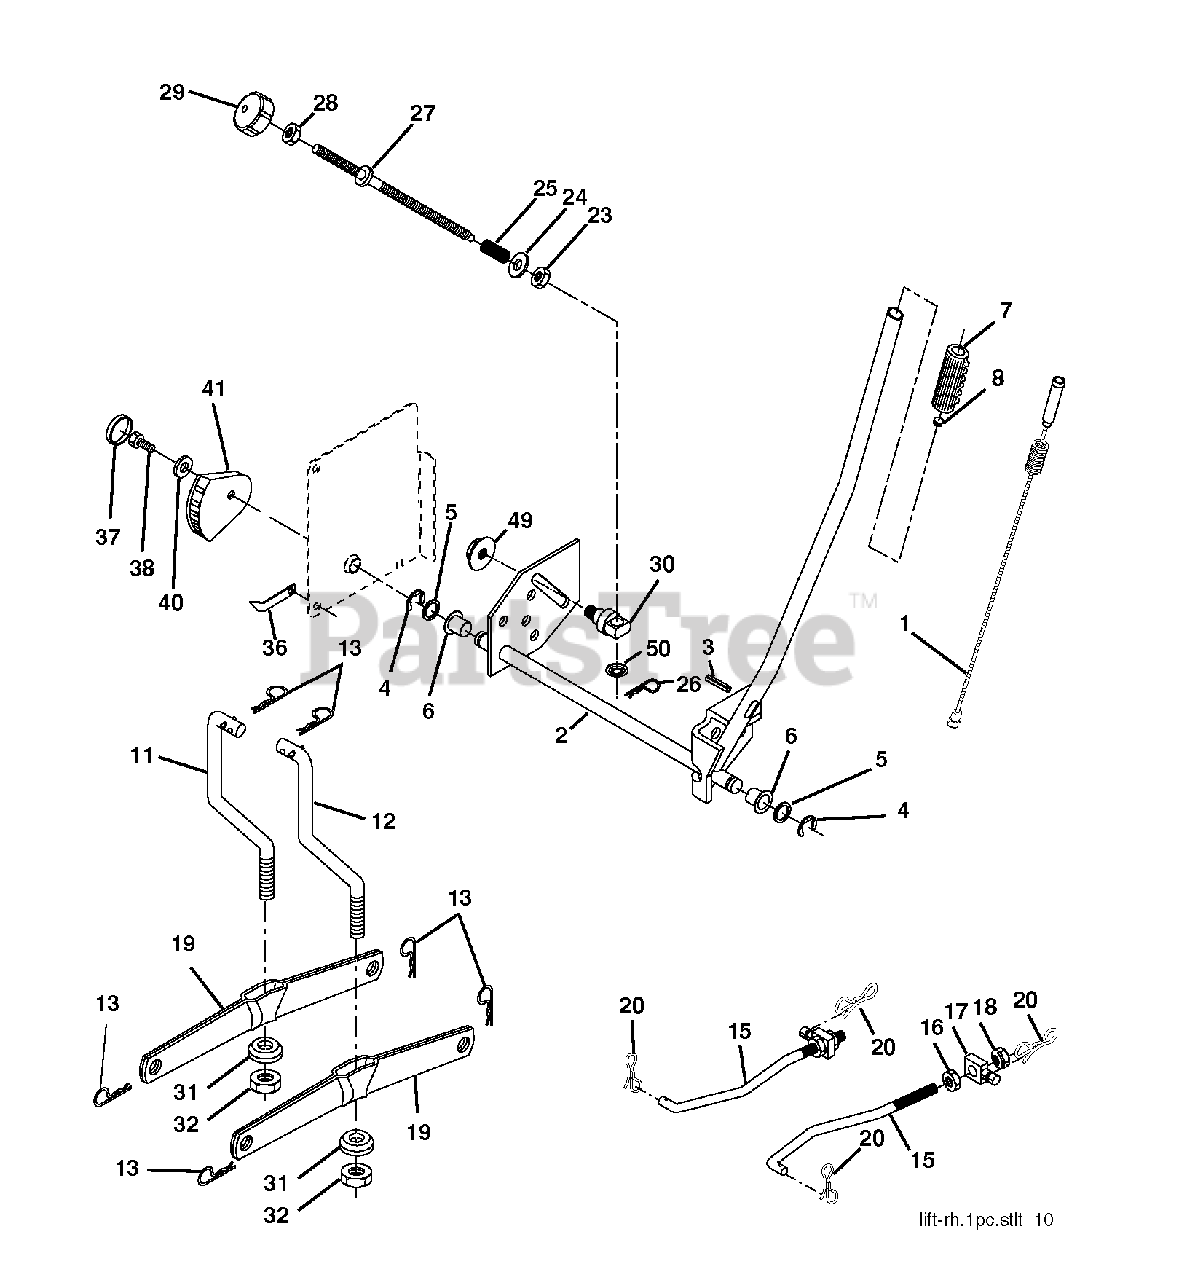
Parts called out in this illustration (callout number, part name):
1	PLUNGER.ASM.LIFT.LEVER.BLK.
2	SHAFT.ASM.LIFT.YT
3	PIN.GROOVE.5/16
4	RETAINING RING LT
6	BEARING.NYLON
7	GRIP HANDLE
8	PLUNGER BUT KIT
11	LINK
12	LINK
13	Retainer Spring
15	LINK.SUSPENSION.FRONT
16	NUT.HEX.JAM.1/2-13
18	NUT.LK.W/WSH.1/2.
19	ARM.REAR.SUSPENSION
20	PIN.COTTER.7/16.BOW TI.
23	Special Nut
26	RETAINER CLIP
27	ROD ADJ LIFT
28	NUT
29	KNOB INF 3/8-16
31	BEARING.PIVOT.LIFT
32	NUT CROWNLOCK 3/8-24
36	POINTER, HEIGHT INDICATOR
38	SCREW 5/16-18X1
41	HEIGHT INDICATOR
49	NUT
50	NUT PUSH M
